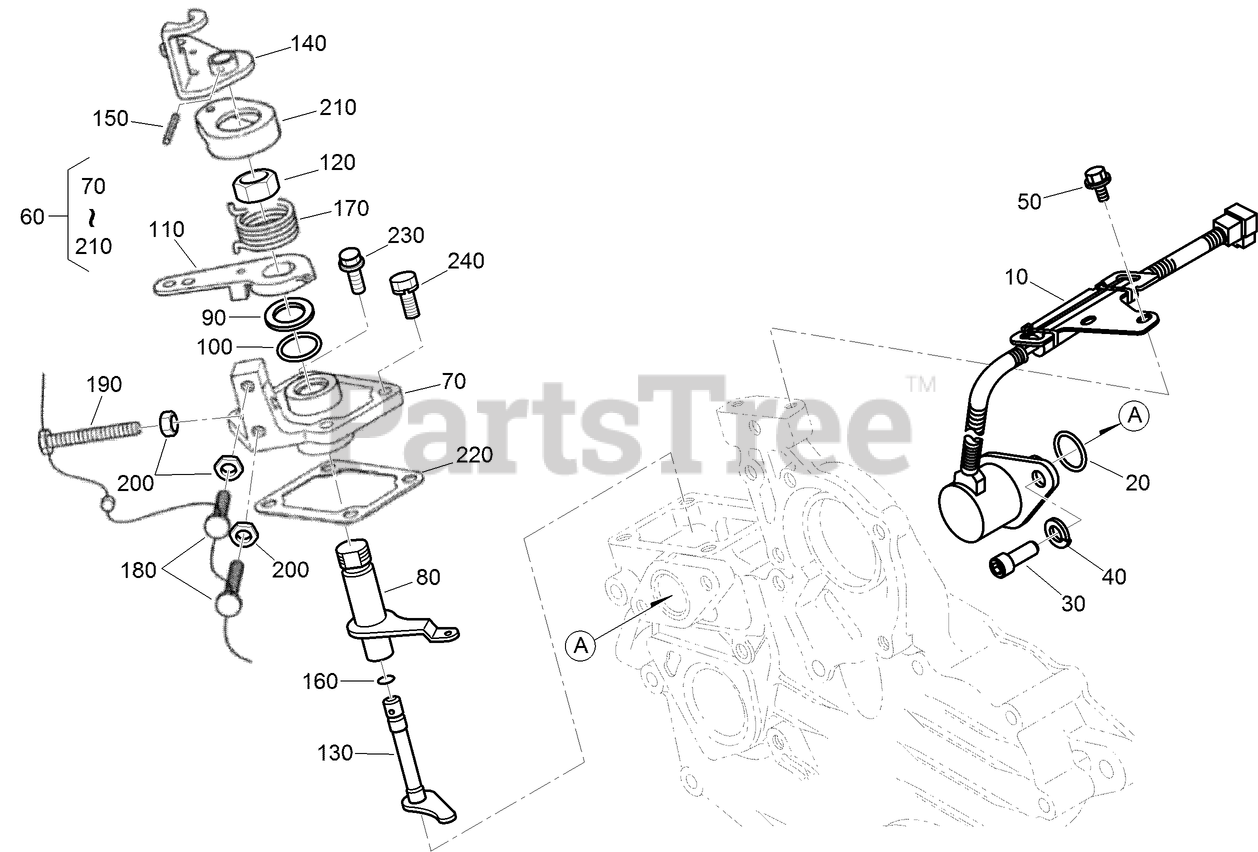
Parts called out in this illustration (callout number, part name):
10	SOLENOID STOP ASM
20	O-RING
30	BOLT-HSH
40	WASHER-SPRING
50	BOLT-FLANGE
60	SPEED CONTROL PLATE ASM
70	PLATE-CONTROL, SPEED
80	LEVER-GOVERNOR
90	COLLAR
100	O-RING
110	LEVER-CONTROL, SPEED
120	NUT-CONTROL, SPEED
130	SHAFT-LEVER
140	LEVER-STOP, ENGINE
150	PIN-SPRING
160	O-RING
170	SPRING-RETURN
180	SCREW-STOPPER
220	GASKET-PLATE, CONTROL
230	BOLT-FLANGE
